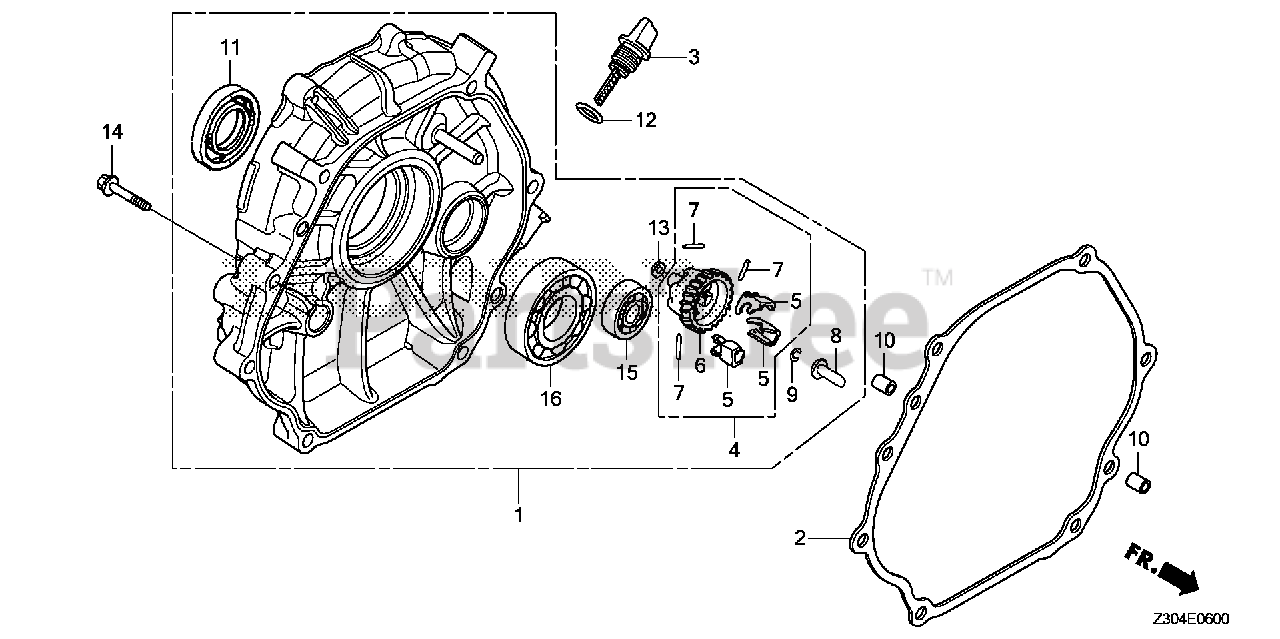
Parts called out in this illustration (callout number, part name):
1	COVER ASSY., CRANKCASE (E-TYPE)
2	GASKET, CRANKCASE COVER
3	CAP, OIL FILLER
4	GOVERNOR ASSY.
5	WEIGHT, GOVERNOR
6	HOLDER, GOVERNOR WEIGHT
7	PIN, GOVERNOR WEIGHT
8	SLIDER, GOVERNOR
9	CLIP, GOVERNOR HOLDER
10	PIN, DOWEL (8X12)
11	OIL SEAL (35X52X8) (NOK)
12	O-RING (26X2.7)
13	WASHER, PLAIN (6MM)
14	BOLT, FLANGE (8X40)
15	BEARING, RADIAL BALL (6202)
16	BEARING, RADIAL BALL (6207)
